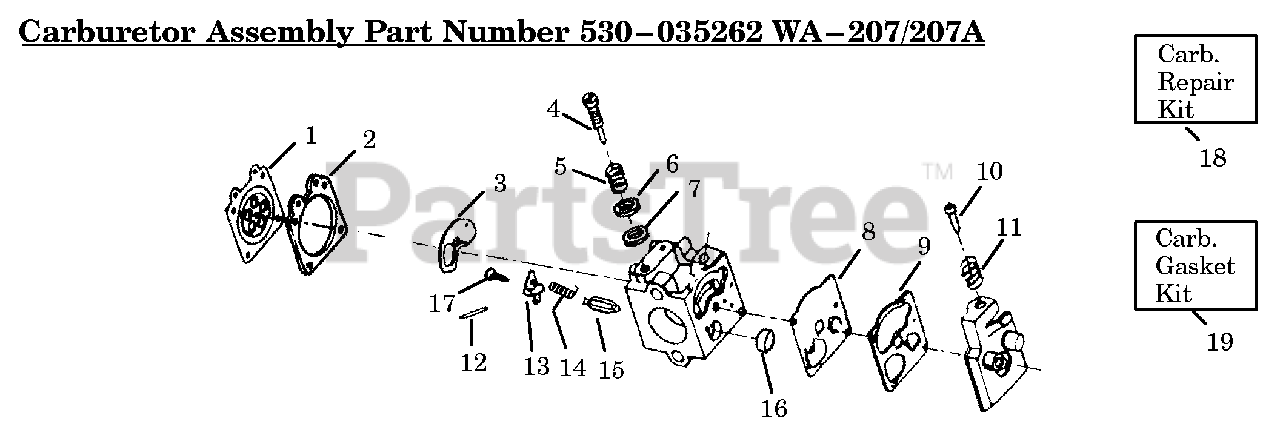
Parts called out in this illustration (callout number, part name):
1	Metering Diaphragm
2	Metering Diaphragm Gasket
3	Circuit Plate Gasket
4	Mixture Needle
5	Mixture Needle Spring
6	Mixture Needle Washer
7	"O" Ring Mixture
8	Fuel Pump Diaphragm
9	Fuel Pump Gasket
10	Idle Speed Screw
11	Idle Speed Spring
12	Metering Lever Pin
13	Metering Lever
14	Metering Lever Spring
15	Inlet Needle Valve
16	Fuel Inlet Screen
17	Metering Lever Pin Screw
18	Carb. Kwik Repair Kit
19	Carb. Gasket/Diaphragm Kit
530035262	Carburetor Assembly (WA207/207A)
